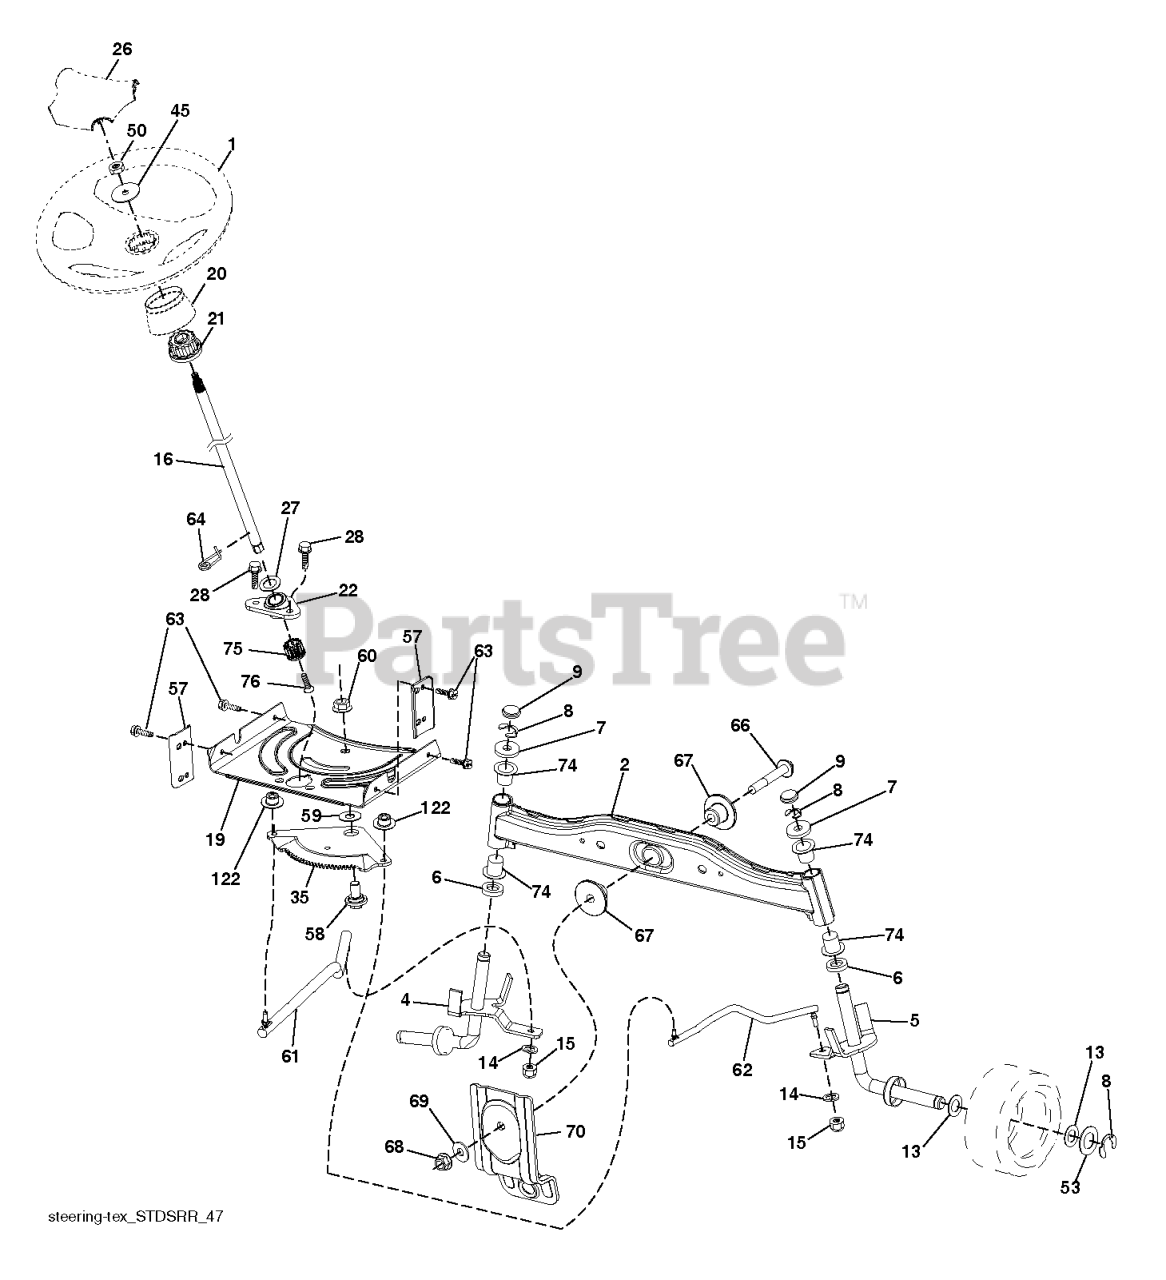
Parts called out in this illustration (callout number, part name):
1	WHEEL.STEERING.HARD.RIM.BLAC
2	AXLE HALF ASM-WELDED
4	SPINDLE.WELDED.LH.15"TEX
5	SPINDLE.WELDED.RH.15"T
6	Bearing Race Thrust Harden (AYP part number)
7	Washer 25/32 x 1-5/8 x 16 Gauge (AYP part number)
8	Ring, Klip #T5304-75 (AYP part number)
9	Cap Spindle Fr Top Blk (AYP part number)
13	Washer 25/32 x 1-1/4 x 16 Gauge (AYP part number)
14	SLW 3/8 STD
15	Nut, Crownlock 3/8-24 (AYP part number)
16	SHAFT.STEER.2HIGH.SPLND.PLATED
19	PLATE.STEER.DDL.NLT/NG
20	BOOT.STRNG.PREDATOR.YT/GT.428
21	ADAPTER.WHEEL.STEER.SPLND.ALUM
22	BEARING.SHAFT.STEER.LOWER.625
26	INSERT, WHEEL STEERING
27	Washer 21/32 x 1 x 16 Gauge (AYP part number)
28	SCREW, 3/8-16X3/4
35	GEAR.SECTOR.PLATE.DDL.
45	WASHER.3/8ID.2-3/8OD.12GA.PLTD
50	NUT LOCK FLG 3/8-16 UNC
53	WASHER.HARDENED
57	BRACKET.UPSTOP.TEX
58	BOLT.SHOULDER.SECTOR.P
59	WASHER.THURST.SECTOR.S
60	NUT FLANGE LOCK 5/8-11
61	DRAGLINK.LH.BALLSTUD.D
62	DRAGLINK.RH.BALLSTUD.D
63	SCREW
64	RETAINER.CLIP.SPRING.S
66	BOLT HEX FGHD 7/16-14 X 3 SERR
67	BUSHING.PM.FRONT AXLE
68	NUT.LOCK.FLANGE.7/16
69	WASHER.1.5X.505X.118
70	BRACKET.FRT.DECK.SUSP.RR.MT431
74	Bearing Col Strg Blk (AYP part number)
75	PINION.ZINC PLATED
76	SCREW HEAD SOCKET LRVB
122	CAP.GEAR.SECTOR.TEX
